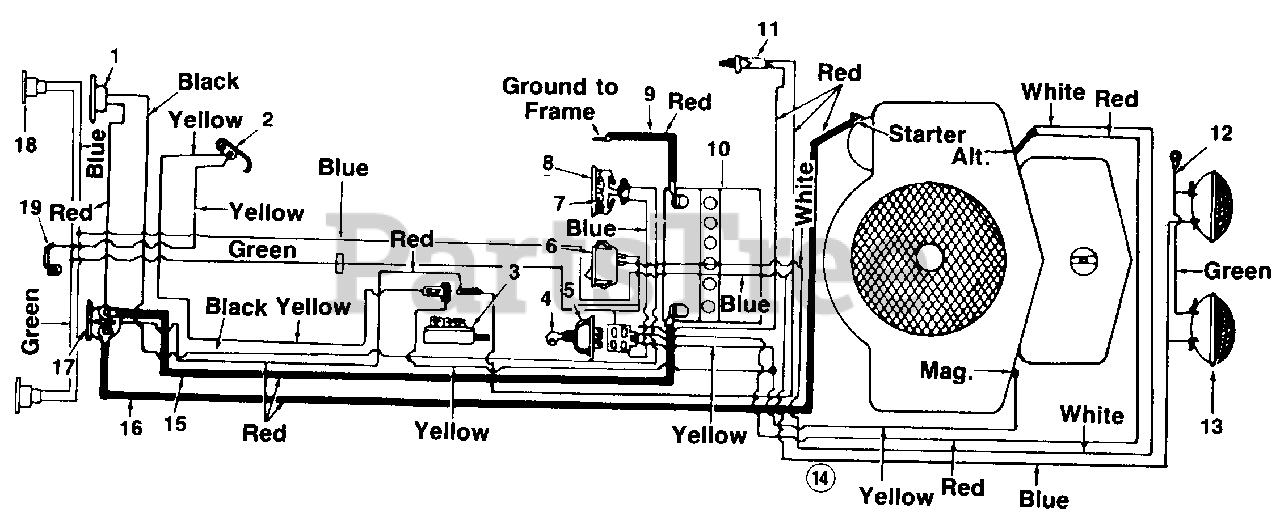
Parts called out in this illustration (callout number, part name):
1	Circuit Breaker
2	Spring Switch
3	Safety Switch Dpst.
4	Ignition Key
5	Ignition Switch
6	Headlight Switch
7	Foam Strip
8	Ammeter
9	Grounding Wire 14.0" Lg.
10	12 Volt Battery
11	Safety Switch
12	Ground Wire
13	Headlight
14	Wire Harness
15	Electric Wire 27.0" Lg.
16	Electric Wire 32.5" Lg.
17	Solenoid
18	Taillight
19	Spring Switch
